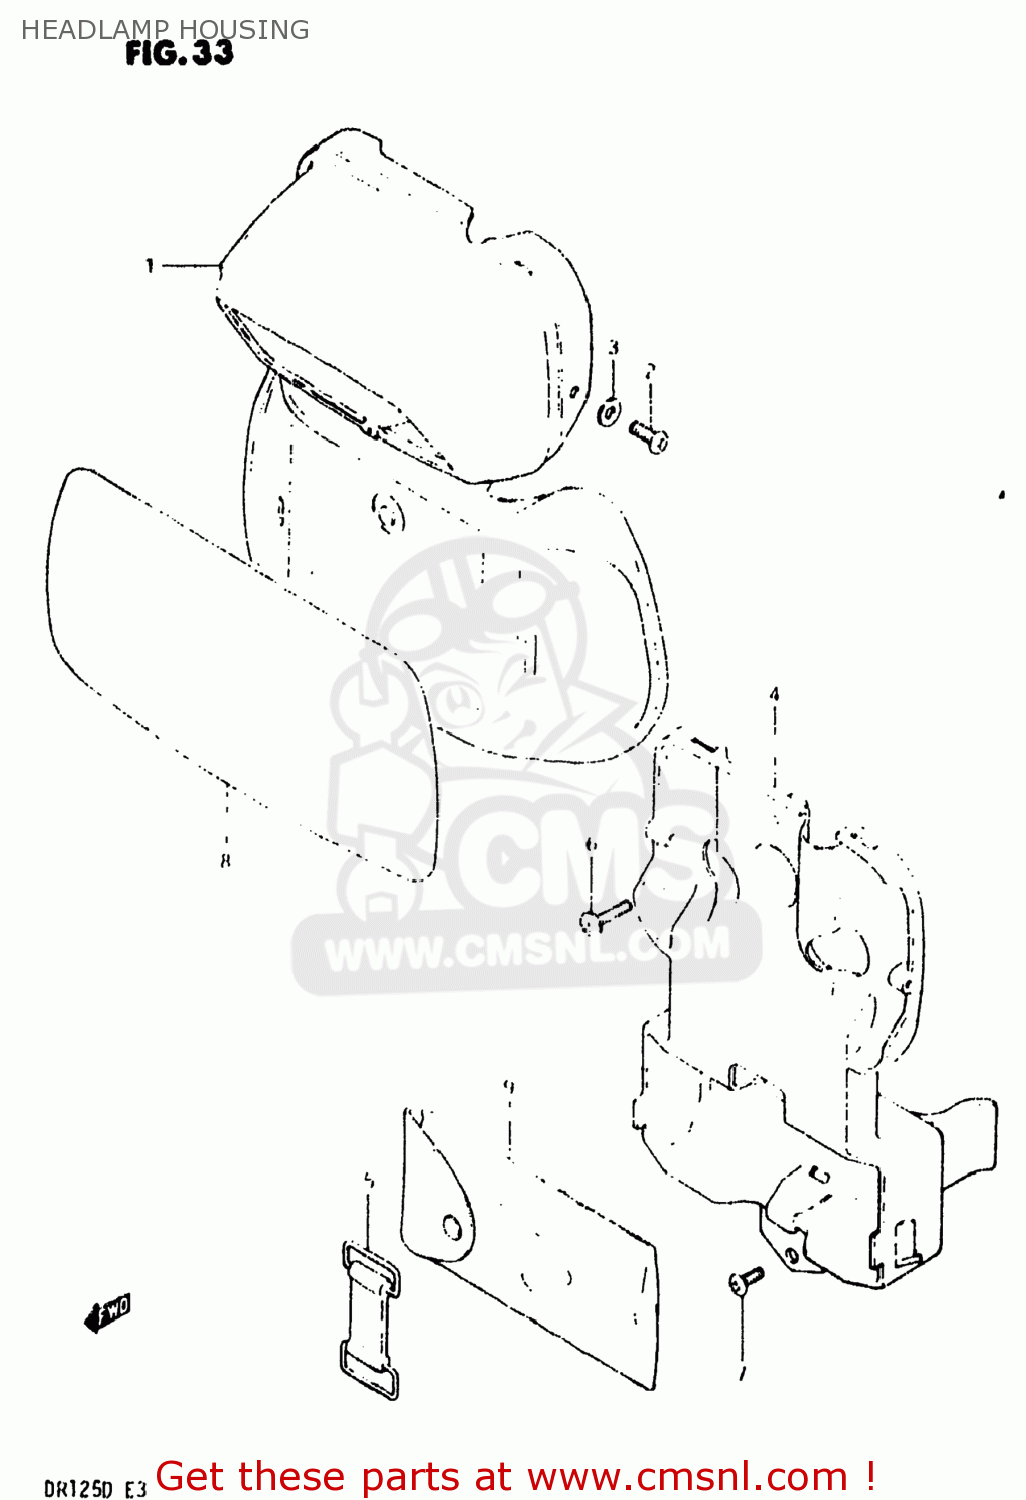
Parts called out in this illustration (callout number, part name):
1	HOUSING,HEADLAMP
2	TAPPING SCREW
3	WASHER
4	HOLDER,TOOL
5	BAND
6	SCREW
7	SCREW
8	EMBLEM,FRONT NUMBER PLATE
9	TOOL SET
